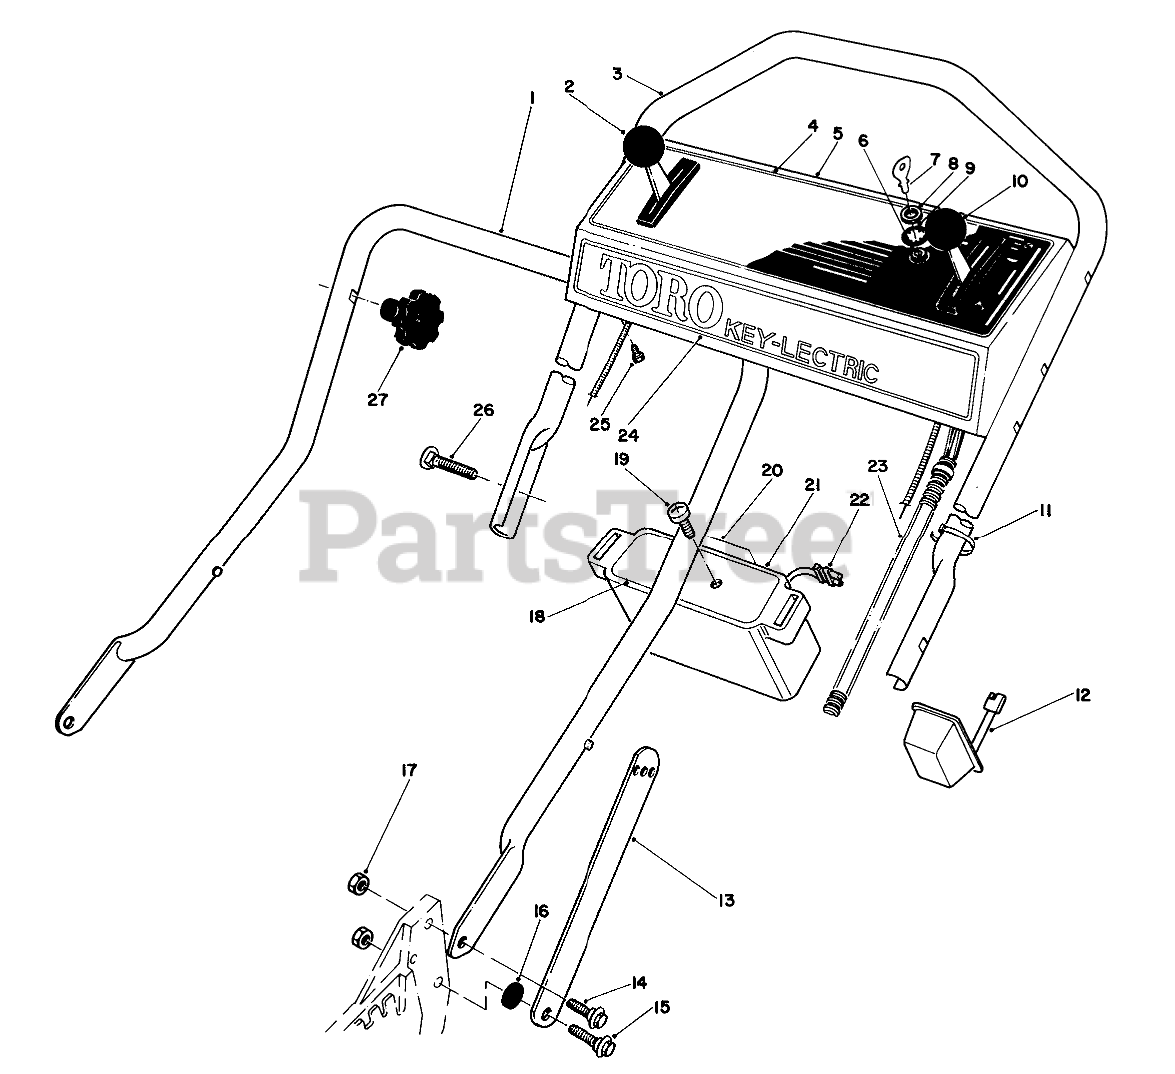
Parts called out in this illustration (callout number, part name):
1	Handle-Lower
2	SERVICE TRACT. CONTROL
3	UPPER HANDLE
4	OBS INSTR PANEL DECAL
5	Control Panel (Incl. Ref. #4)
6	STARTER SWITCH ASM
7	Key
8	NUT-HH
9	WASHER-TOOTH, INTERNAL
10	SERVICE THROTTLE CONTRO
11	TIE-CABLE
12	Charger
13	Handle Latch
14	SCREW-SHOULDER
15	SCREW-SHOULDER
16	SPACER
17	NUT-LOCK, NI
18	BATTERY COVER
20	Decal
21	Battery Case
22	Plug & Wire
23	Wire Harness
24	Decal-Toro
25	SCREW-HWHTF
26	5/16-18 X 2 HNDLE SCREW
